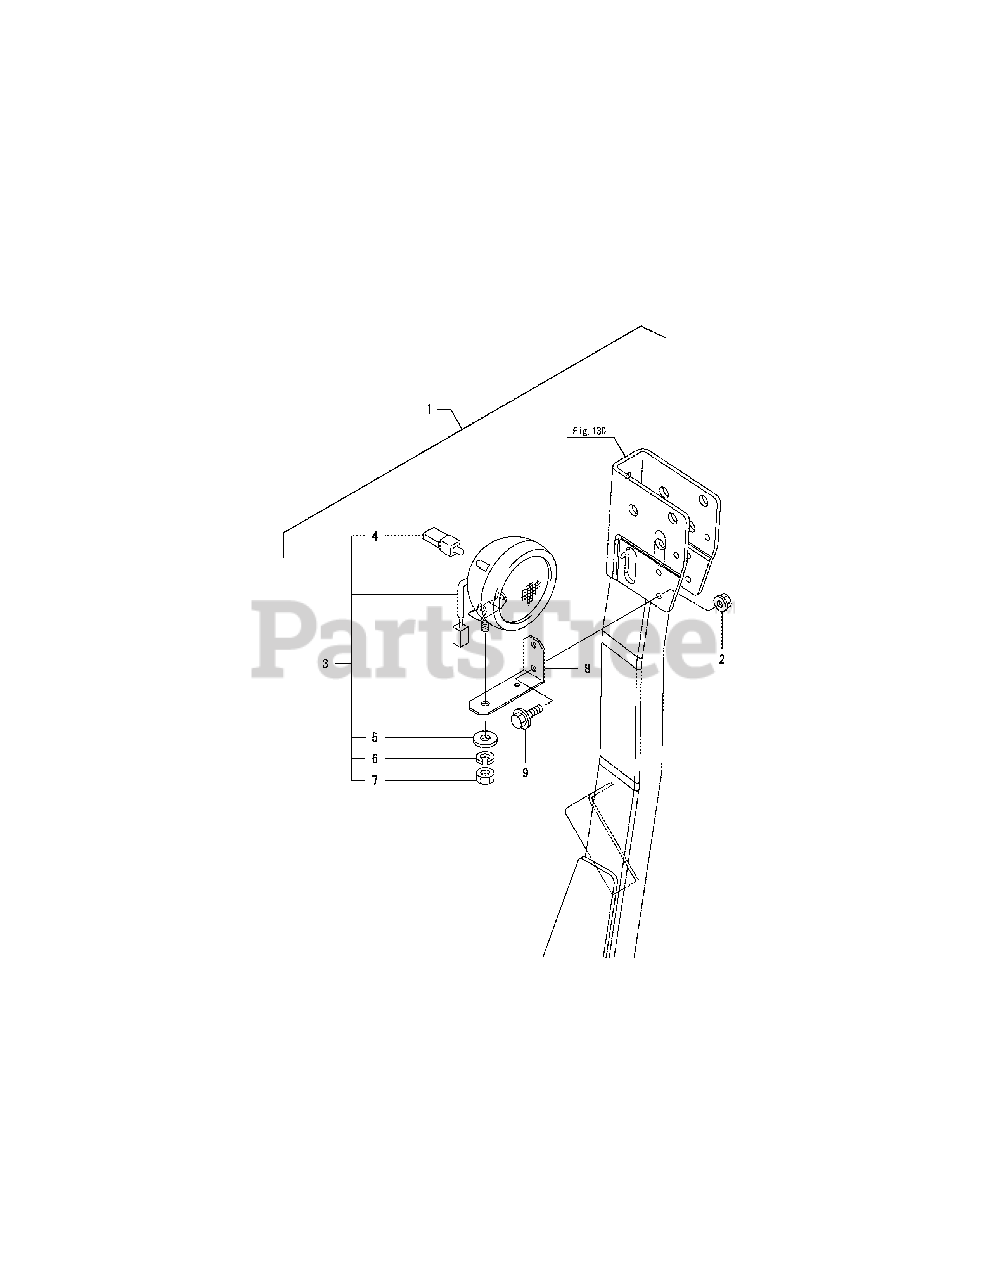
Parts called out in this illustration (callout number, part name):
2	NUT W/WASHER 8
3	WORK LAMP ASSY, SW
5	WASHER 10, POLISHED
6	SPRING WASHER 10
8	STAY, WORK LAMP
9	BOLT M 8X 20 PLATED
